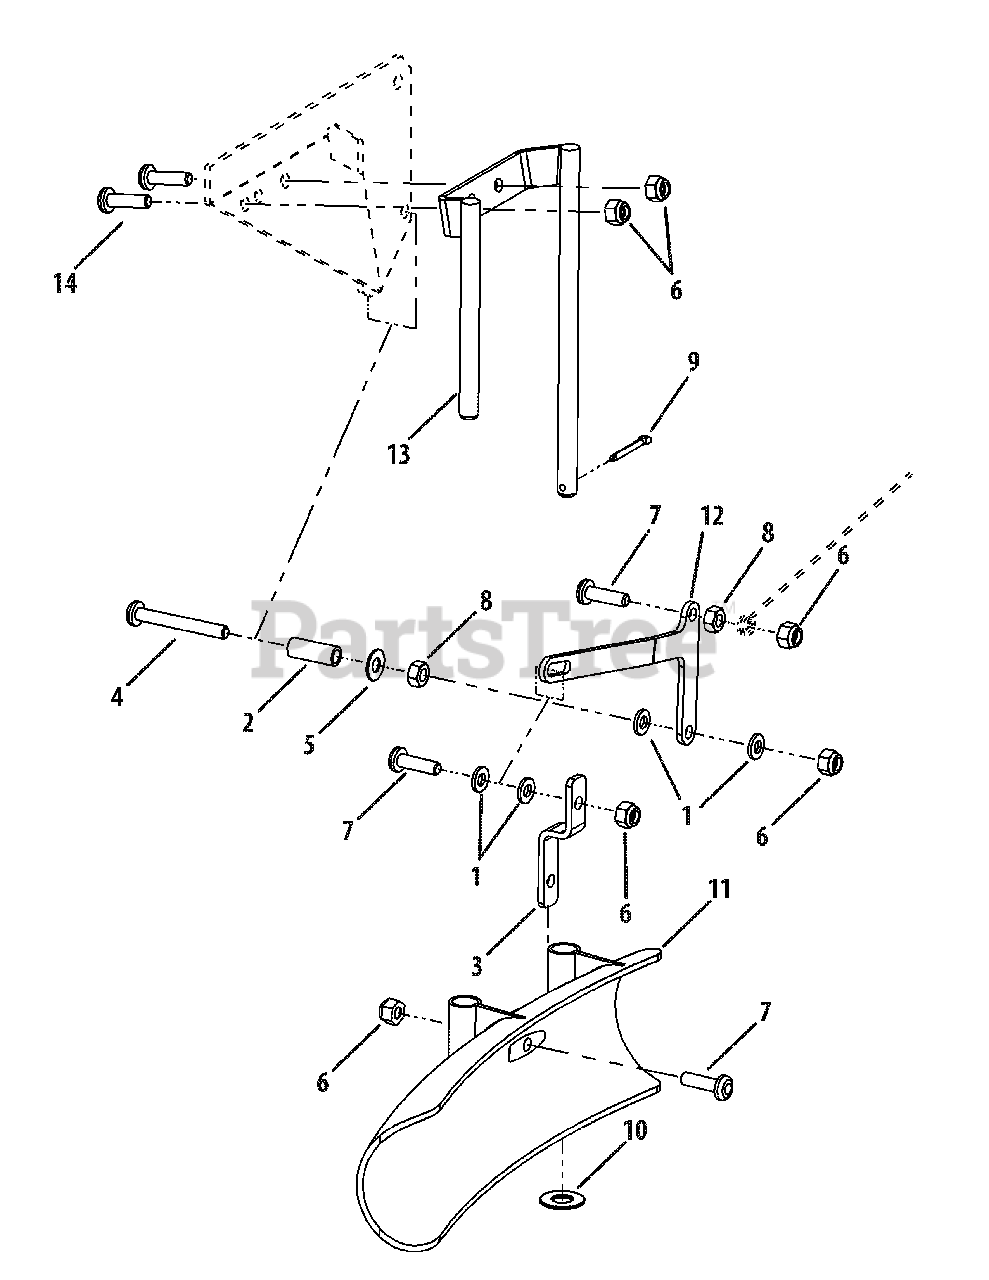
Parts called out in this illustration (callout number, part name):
1	Washer, 1/4
2	Deflector Arm Spacer
3	Offset Deflector Bracket
4	Machine Screw, 1/4-20 x 2
5	Washer, 1/4, SS
6	Nut, 1/4, SS
7	Machine Screw, 1/4-20 x 7/8
8	Nut, 1/4-20
9	Cotter Pin, 1/8 x 1, SS
10	Washer, 3/8, SS
11	Deflector Tube
12	Deflector Mount Lever
13	Deflector Mount Weldment
14	Socket Head Screw, 1/4-20 x 7/8
